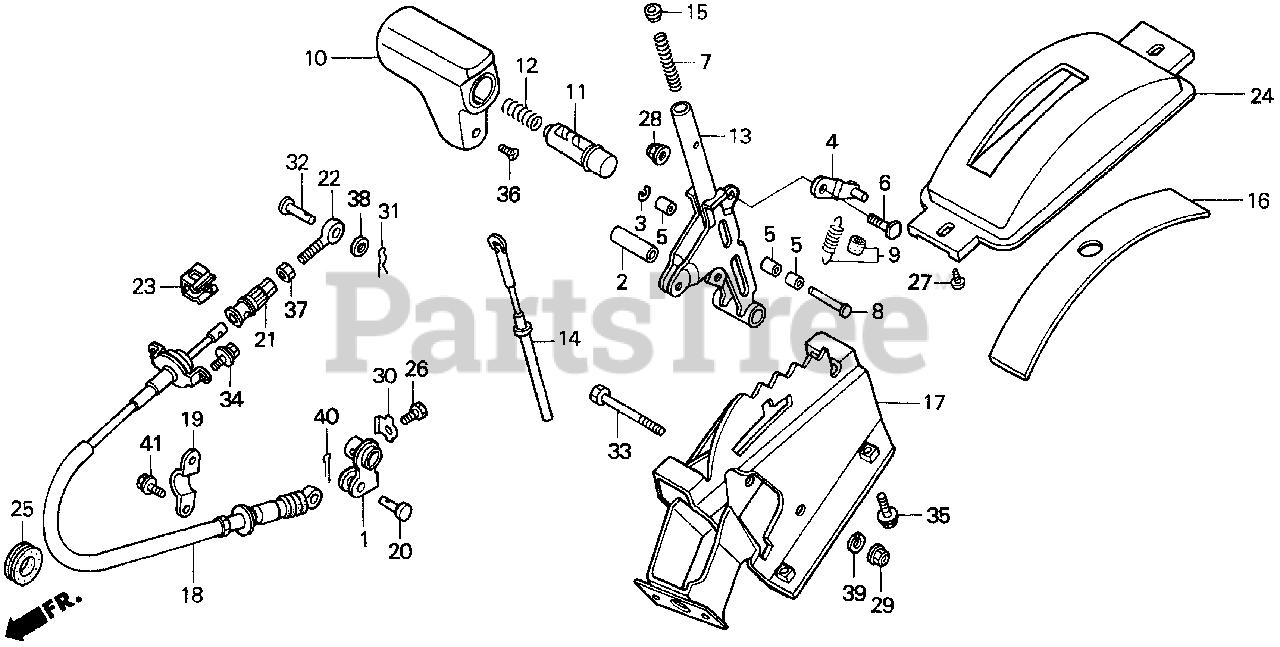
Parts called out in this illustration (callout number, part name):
1	LEVER, CONTROL
2	SHAFT A, STARTING IDLE
3	E-CLIP (3MM)
4	STOPPER, SELECT LEVER
5	COLLAR, LOCK PIN
6	BOLT, SELECTOR STOPPER
7	SPRING, LOCK PIN
9	SPRING ASSY., SELECT
10	KNOB, SELECT LEVER
11	KNOB, PUSH
12	SPRING, PUSH KNOB
13	LEVER, SELECT
14	ROD, LOCK PIN
15	BUSH, GUIDE
16	COVER, SELECT LEVER
17	BRACKET, CONTROL
18	WIRE, CONTROL
19	HOLDER, CONTROL WIRE
20	PIN A, CONTROL ROD
21	PIPE, CONTROL WIRE ADJUSTING
21	PIPE, WIRE ADJUSTING
22	END, ROD (6MM)
23	PIN, CONTROL WIRE ADJUSTER
24	CONTROL *NH24* (ESCN) (CERAMIC WHITE)
25	GROMMET, CABLE
26	BOLT, HEX. (6MM)
27	SCREW, RR. COVER
28	NUT, SELF-LOCK (6MM)
29	NUT, SELF-LOCK (6MM)
30	WASHER, LOCK (6MM)
31	PIN, SNAP (6MM)
32	PIN, SIDE CLUTCH ARM
33	BOLT, HEX. (6X50)
34	BOLT-WASHER (6X16)
35	BOLT-WASHER (6X12)
36	SCREW, OVAL (5X8)
37	NUT, HEX. (6MM)
38	WASHER, PLAIN (6MM)
39	WASHER, SPRING (6MM)
40	PIN, COTTER (1.6X25)
41	BOLT, FLANGE (6X14)
